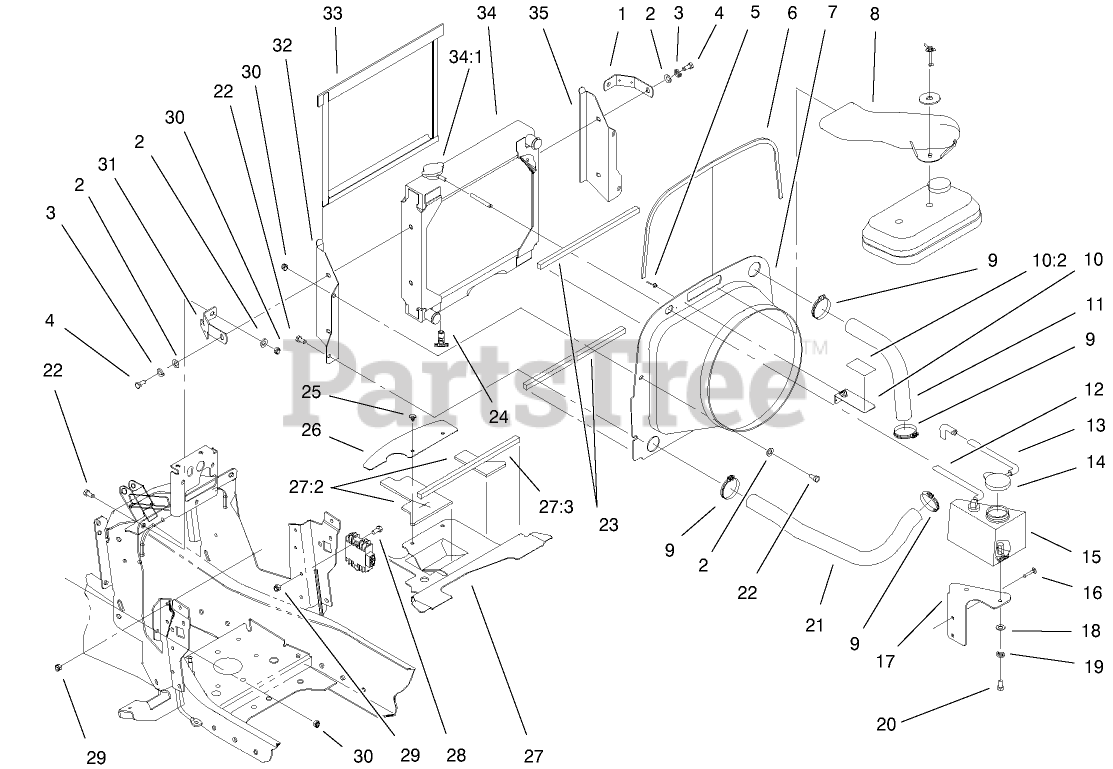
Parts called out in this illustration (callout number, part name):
2	WASHER-PLAIN
3	WASHER-LOCK
4	SCREW-HH
5	RIVET-POP
6	TRIM - LOC 31"
7	SHROUD - FAN
8	DUCT - AIR, KAWASAKI
9	CLAMP-HOSE
10	FAN/DECAL ASM
10:2	DECAL - WARNING
13	HOSE - OVERFLOW
15	BOTTLE - OVERFLOW
16	BOLT-CARR
18	WASHER-FLAT
19	WASHER-LOCK
20	SCREW-HH
21	HOSE - RAD. KAWASKI
22	SCREW-HH
23	FOAM - RADIATOR/SHROUD
25	RIVET - PLASTIC
26	BAFFLE - TOWER REAR
27	BAFFLE-TOWER ASM
27:2	FOAM - BAFFLE
27:3	FOAM - RADIATOR/SHROUD
28	SCREW-HH
29	NUT-HEX
30	NUT-LOCK, NI
34	RADIATOR - GAS
34:1	CAP-RADIATOR
